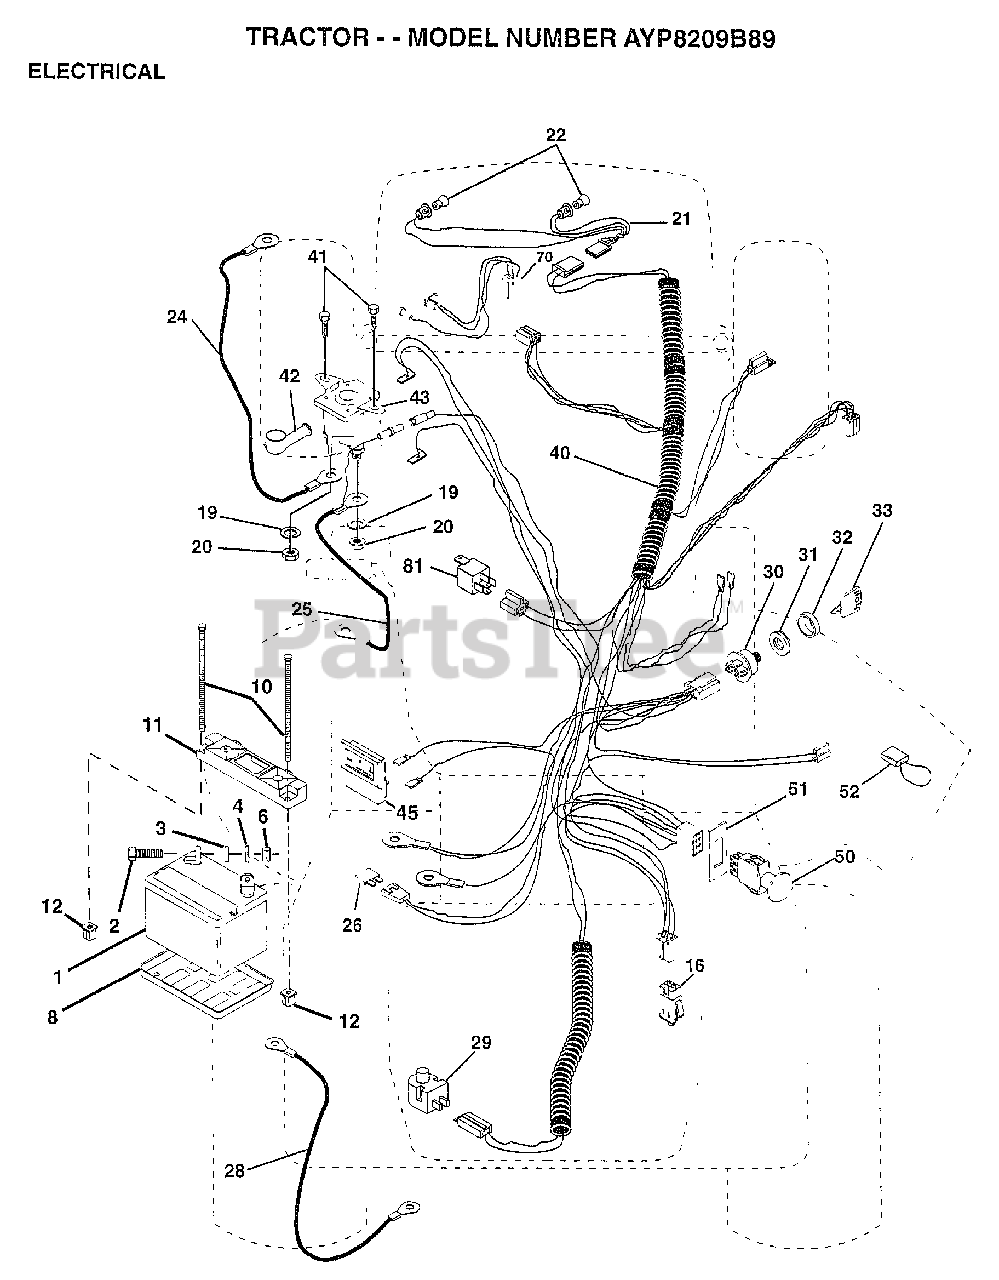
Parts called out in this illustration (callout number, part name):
2	BOLT LT
3	WASHER
4	LOCKWASHER
8	"TRAY T, BATTERY"
11	HOLDDOWN BATTERY
16	SWITCH INTERLOCK
20	NUT
21	"HARNESS,LIGHT SOC"
22	HEADLAMP BULB
24	CABLE-BATTERY T
25	CABLE.6GA.12.5.
26	FUSE HYT
28	CABLE T
29	SWITCH.PLUNGER
30	SWITCH IGN 4POS
31	NUT IGNITION
32	COVER KEY SWITCH
33	KEY
40	HARNESS.IGNITON
41	SCREW
45	AMMETER
50	PTO SWITCH.BLK
51	RING RETAIN PTO
52	PROTECTION LOOP
70	HARNESS.ENGINE
81	RELAY ASSY T
